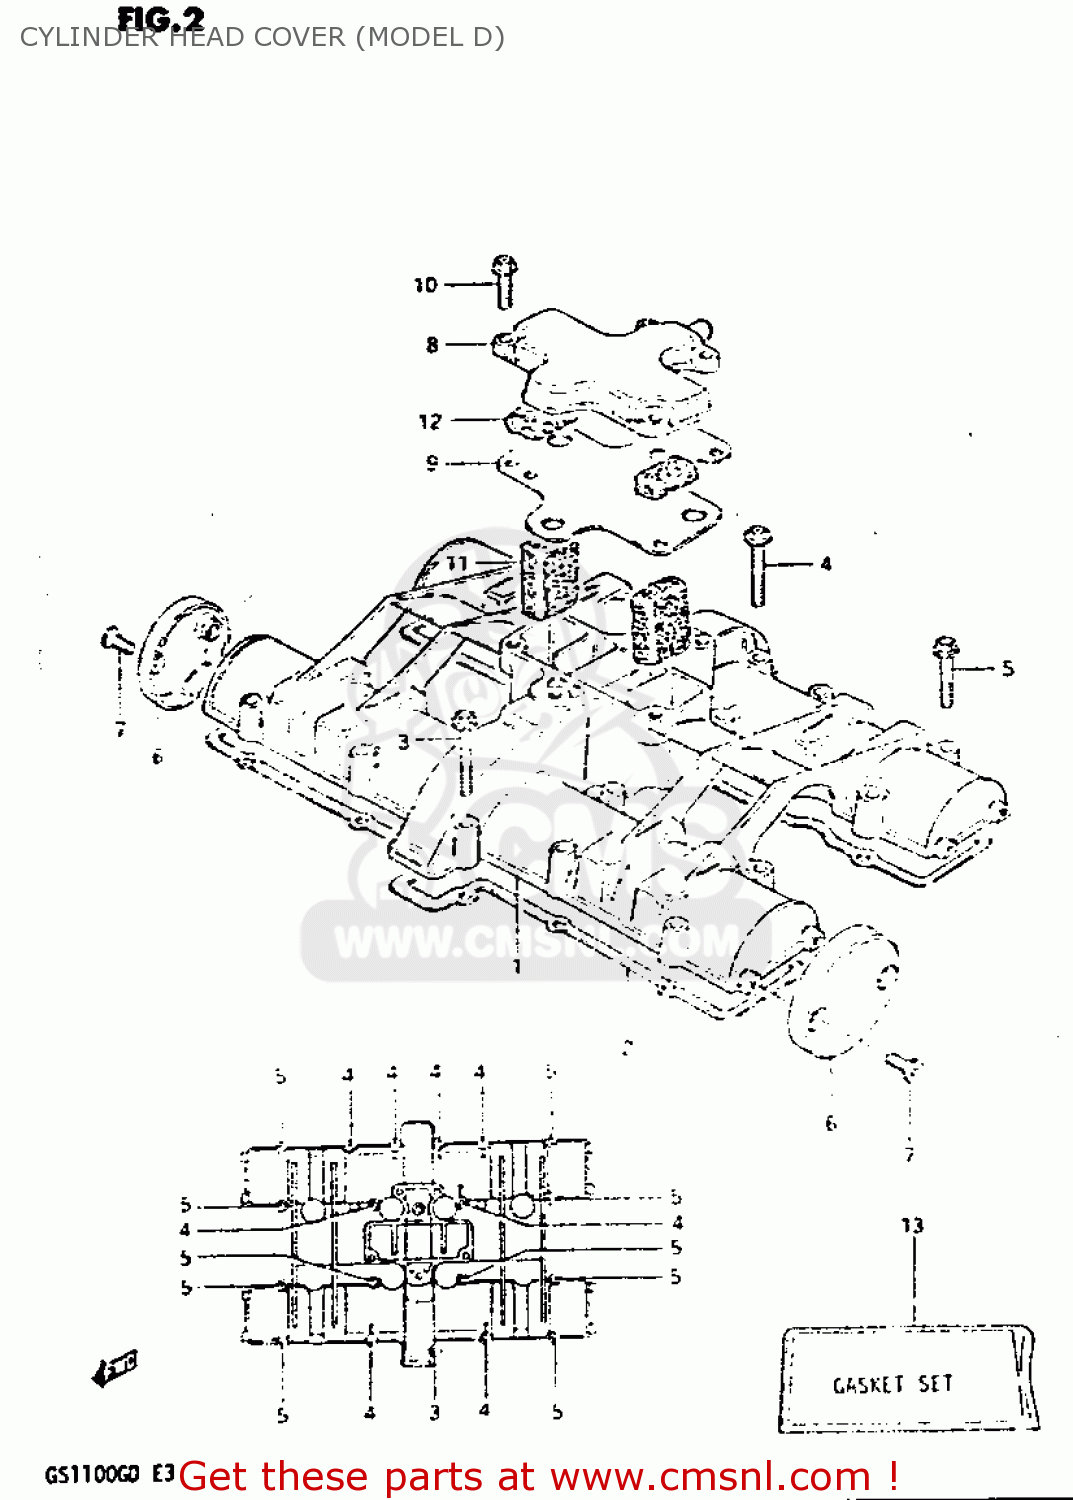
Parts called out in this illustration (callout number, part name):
1	COVER,CYLINDER HEAD
2	GASKET,CYL HEAD COVER (NAS)
3	BOLT (6X45)
4	BOLT
5	BOLT 6X35
6	CAP,CYLINDER HEAD COVER
7	SCREW(5X12)
8	COVER,BREATHER
9	GASKET (MCA)
10	BOLT 6X20
11	COVER,BREATHER
12	SEPARATOR,OIL BREATHER
13	GASKET SET
